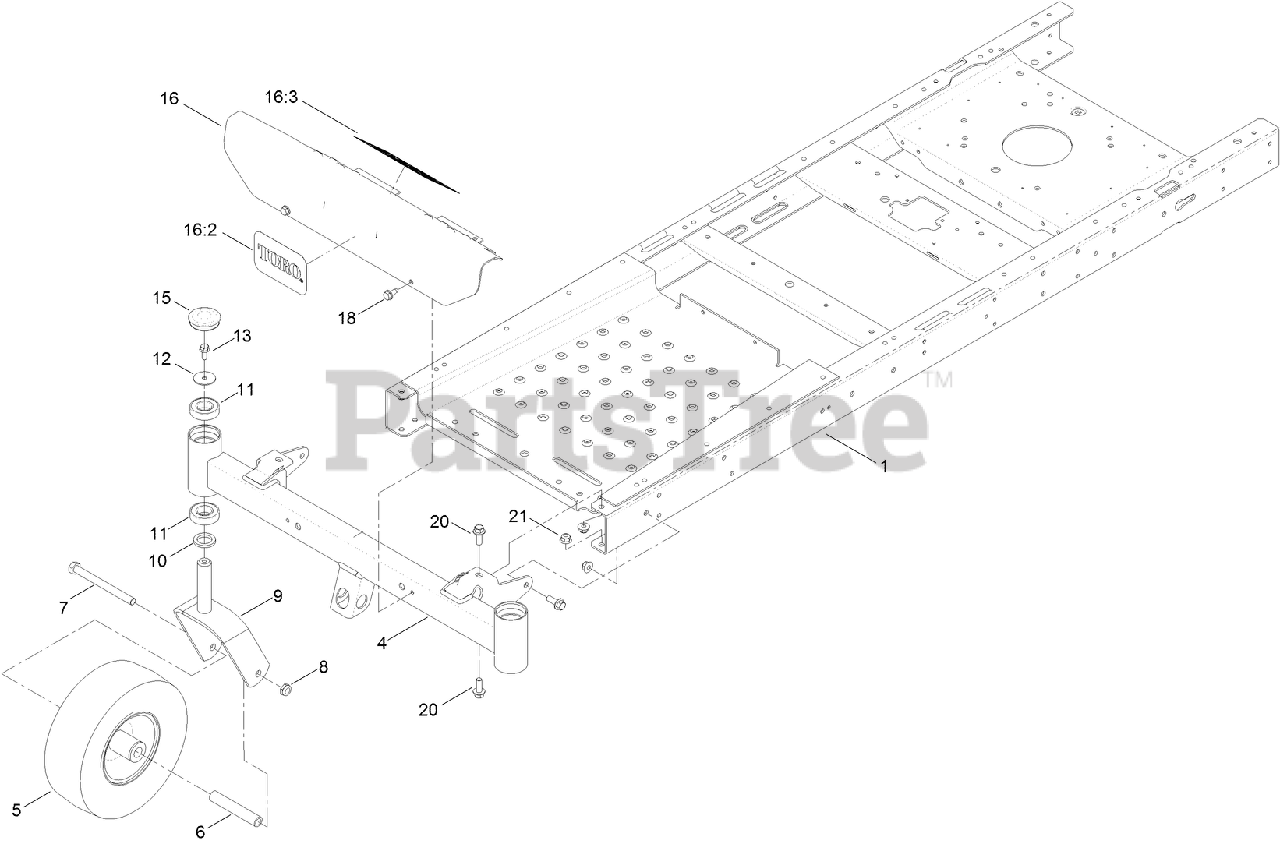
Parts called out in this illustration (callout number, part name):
1	FRAME ASM
4	AXLE-FRONT, NARROW
5	CASTER WHEEL ASM
6	BUSHING-SPANNER
7	SCREW-HH
8	NUT-HEX
9	CASTER FORK ASM
10	WASHER-THRUST
11	BEARING-BALL
12	WASHER-FLAT
13	SCREW-HHF
15	CAP-GREASE
16	FOOTREST ASM
16:3	DECAL-DANGER
18	SCREW-HWHTF
20	SCREW-HHF
21	NUT-HF, NI
